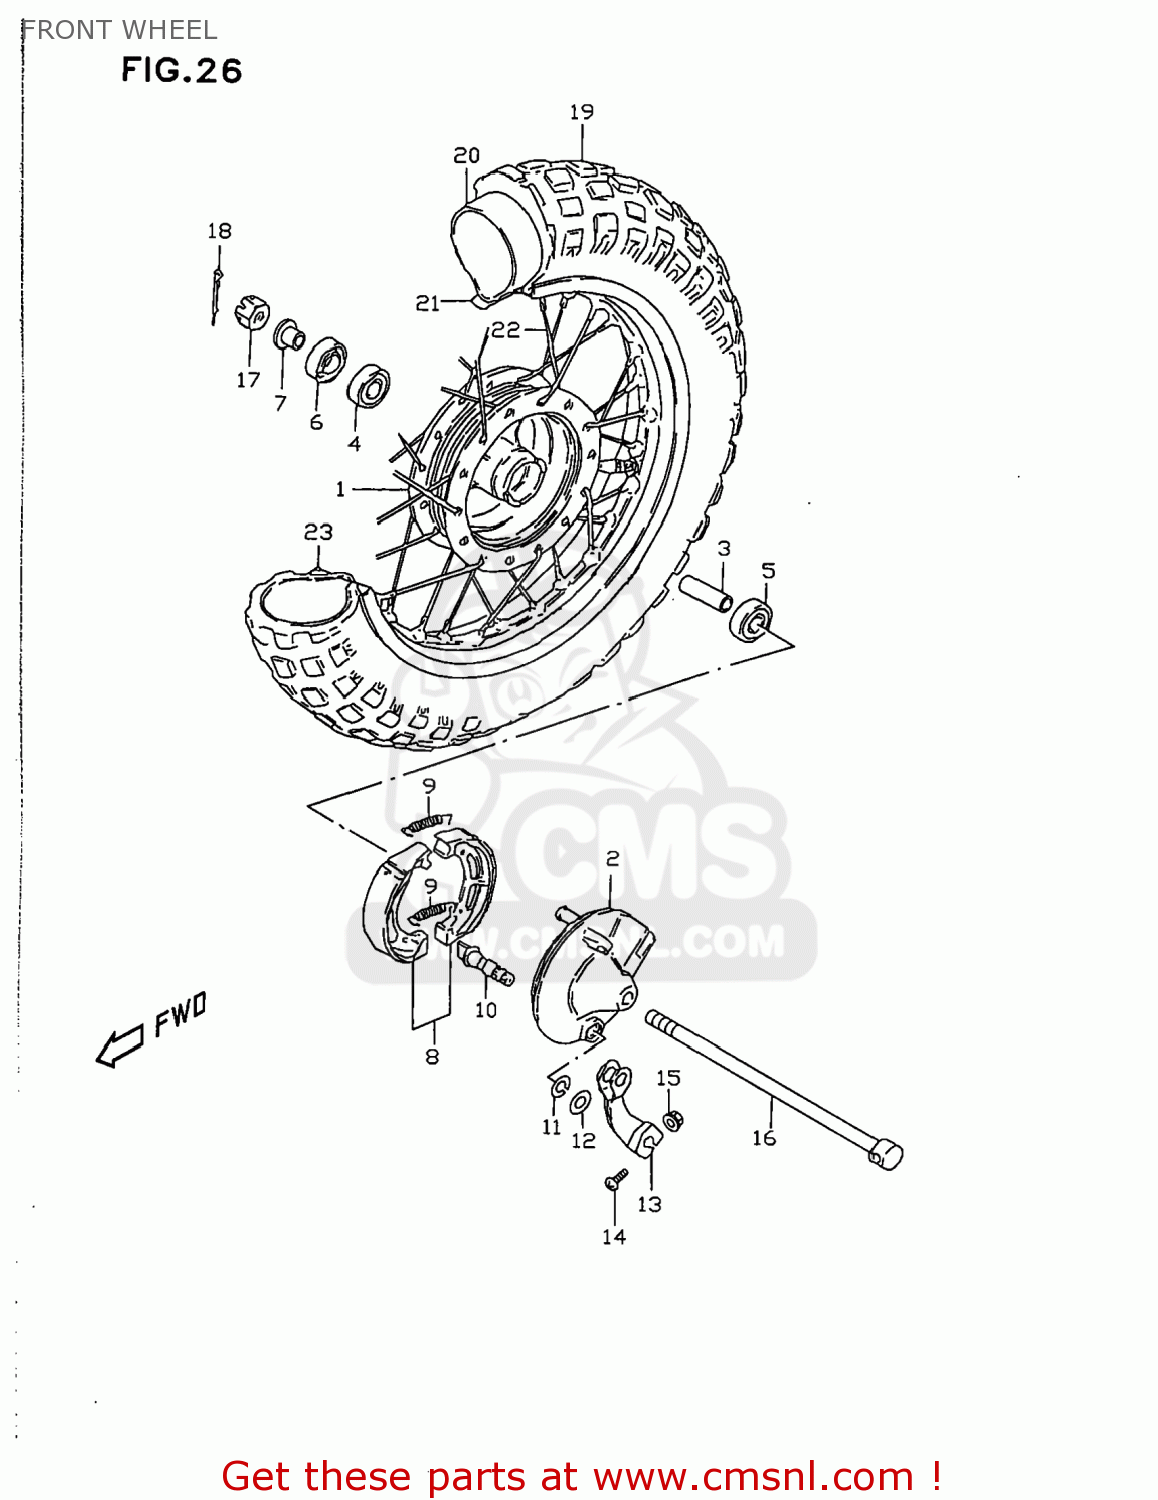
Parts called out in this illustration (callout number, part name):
1	HUB,FR WHEEL
2	PANEL,FR BRAKE ANCHOR
3	SPACER(10.2X16X47)
4	BEARING(10X26X8)
5	BEARING
6	SEAL,OIL(15X27X6)
7	SPACER,AXLE
8	SHOE & SPRING SET (NAS)
9	SPRING(L:35.8)
10	CAM,BRAKE
11	O RING(D:2.4,ID:9.6)
12	WASHER(10.5X18X1)
13	LEVER,FR BRAKE CAM
14	BOLT
15	NUT
16	AXLE,RR
17	NUT
18	PIN 20X20
19	TIRE
20	TUBE,INNER
21	PROTECTOR,INNER TUBE
22	SPOKE SET,RR
23	RIM,WHEEL
